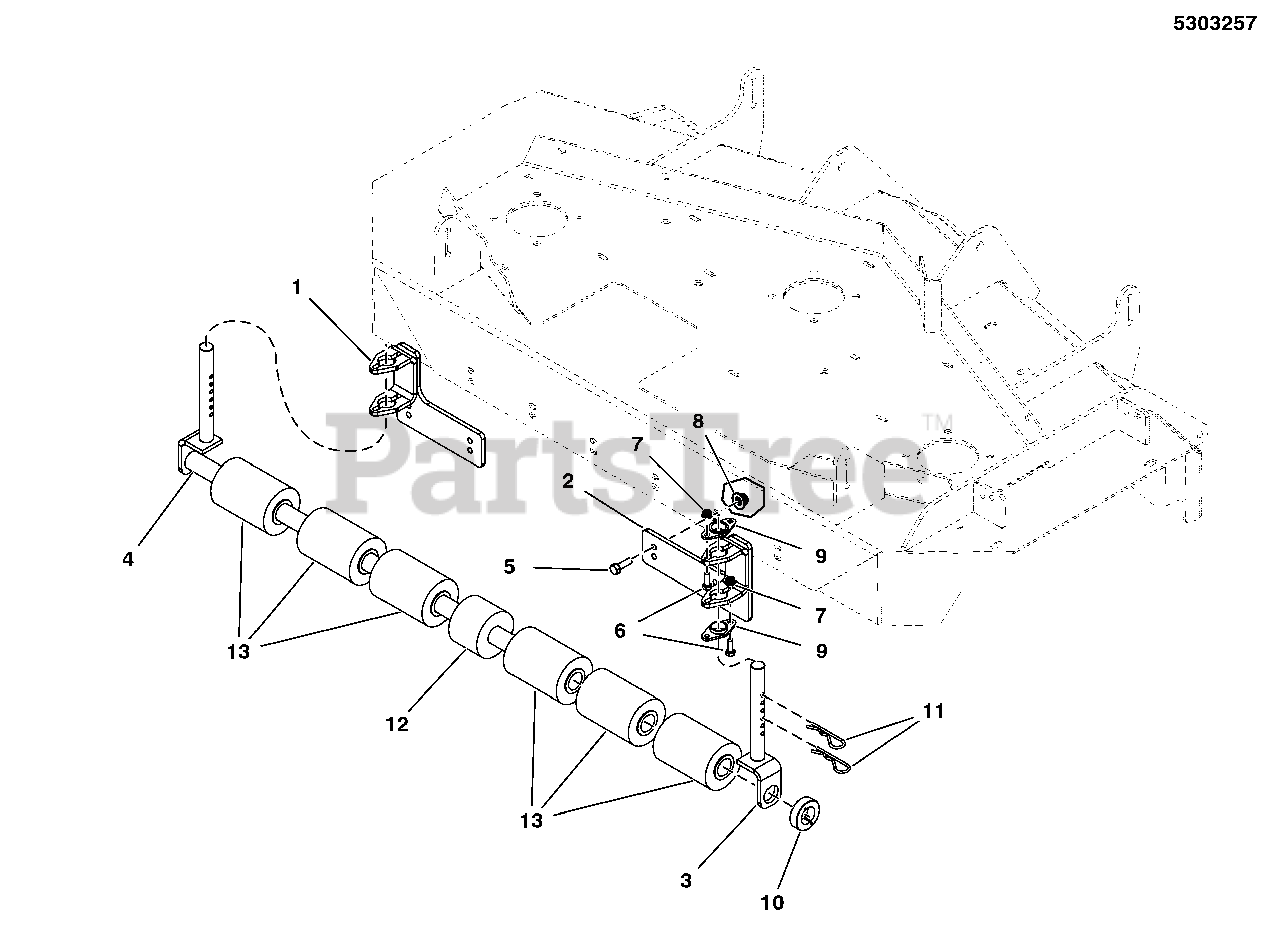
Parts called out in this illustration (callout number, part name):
1	WELD, ROLLER MOUNT LH, 48, IS600 - BLK
2	WELD, ROLLER MOUNT RH, 48, IS600 - BLK
3	WELD, ROLLER SUPPORT, 48, IS600 - BLK
4	WELD, ROLLER SHAFT, 48, IS600 - BLK
5	BOLT, 5/16-18 X 1 GD5 YZ
6	BOLT, 1/4-20 X 3/4 GD5 YZ
7	NUT, 1/4-20 HEX NYLOCK FLANGE (5025391)
8	NUT, 5/16-18 HEX SERRATED FLANGE (SMALL)
9	BUSHING, FLANGE, GFL - 20
10	COLLAR, 1 SPLIT
11	CLIP-HAIR PIN .125DIA SPRG WI 2.56LG BLK
12	ROLLER-1.010ID 2
13	ROLLER W/BUSHINGS BLACK POLY
